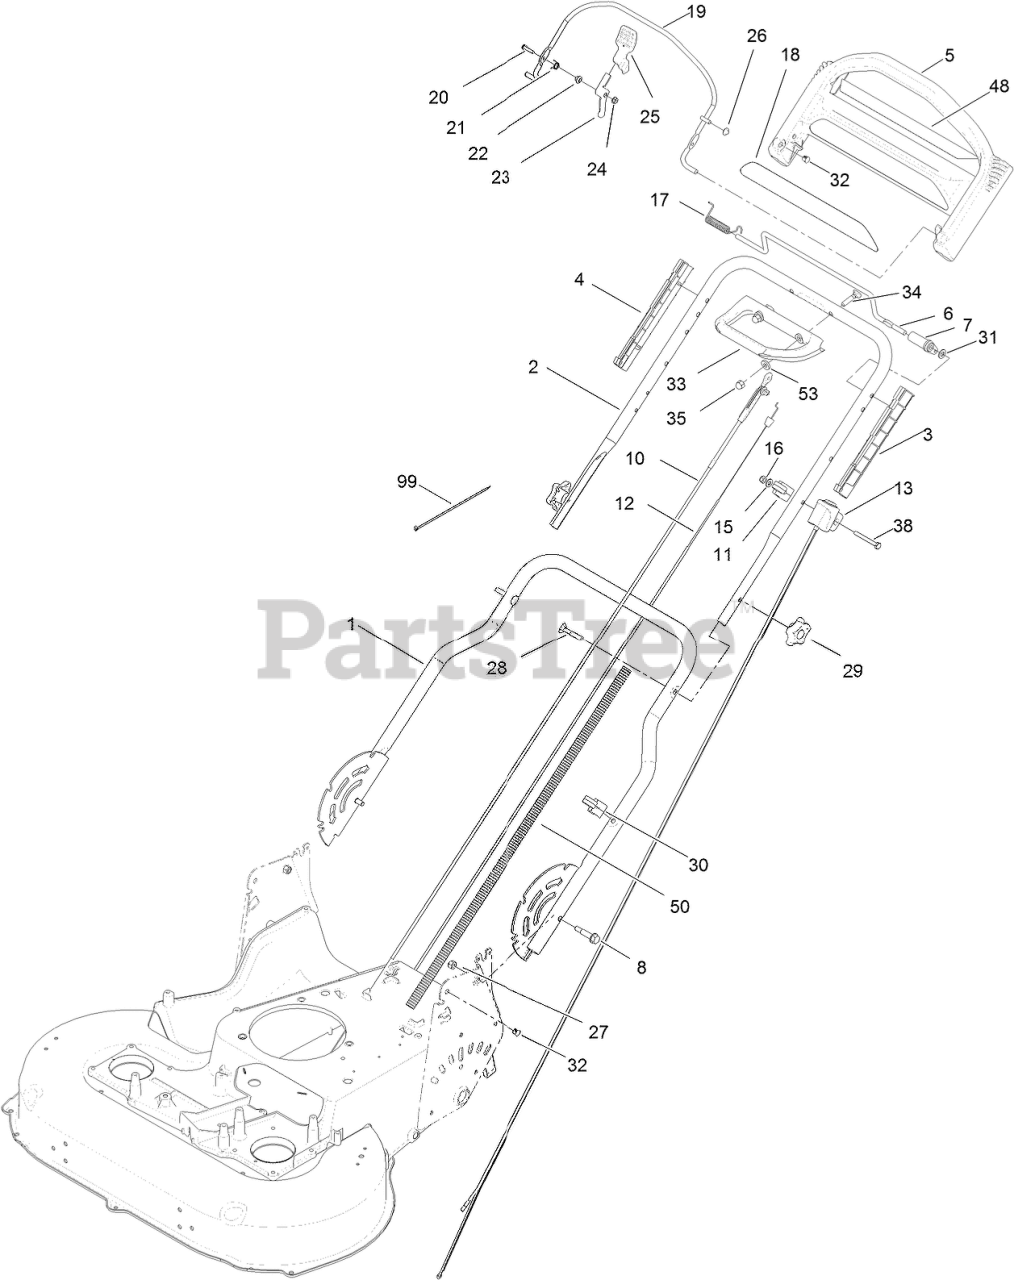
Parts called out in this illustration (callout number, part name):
1	HANDLE-LOWER
2	HANDLE-UPPER
3	GUIDE-LH
4	GUIDE-RH
5	HANDLE-CONTROL
6	BAR-CONTROL, TRACTION
7	LEVER-TRACTION
8	BOLT-SHOULDER, HHF
10	CABLE-BRAKE, BBC
11	ANCHOR-CABLE
12	CABLE-TRACTION
13	SWITCH HOUSING ASM
15	WASHER-FLAT
16	NUT-LOCK, NI
17	Spring-Torsion
19	BAIL-BRAKE
20	SCREW-HWH
21	SPRING-TORSION
22	SPACER
23	LEVER
24	NUT-LOCK, FLANGE
26	NUT-SPEED
27	NUT-LOCK, NI
28	SCREW-HANDLE
29	KNOB-HANDLE
30	GUIDE-CABLE
31	WASHER-PLAIN
32	Plug-Dome
33	HANDLE-ASSIST, TRACTION
34	SCREW-HANDLE, LOCK
35	NUT-ACORN
38	SCREW-HH
48	DECAL-ASSIST, TRACTION
50	CONDUIT-CONVOLUTED
53	WASHER-PLAIN
99	TIE-CABLE
